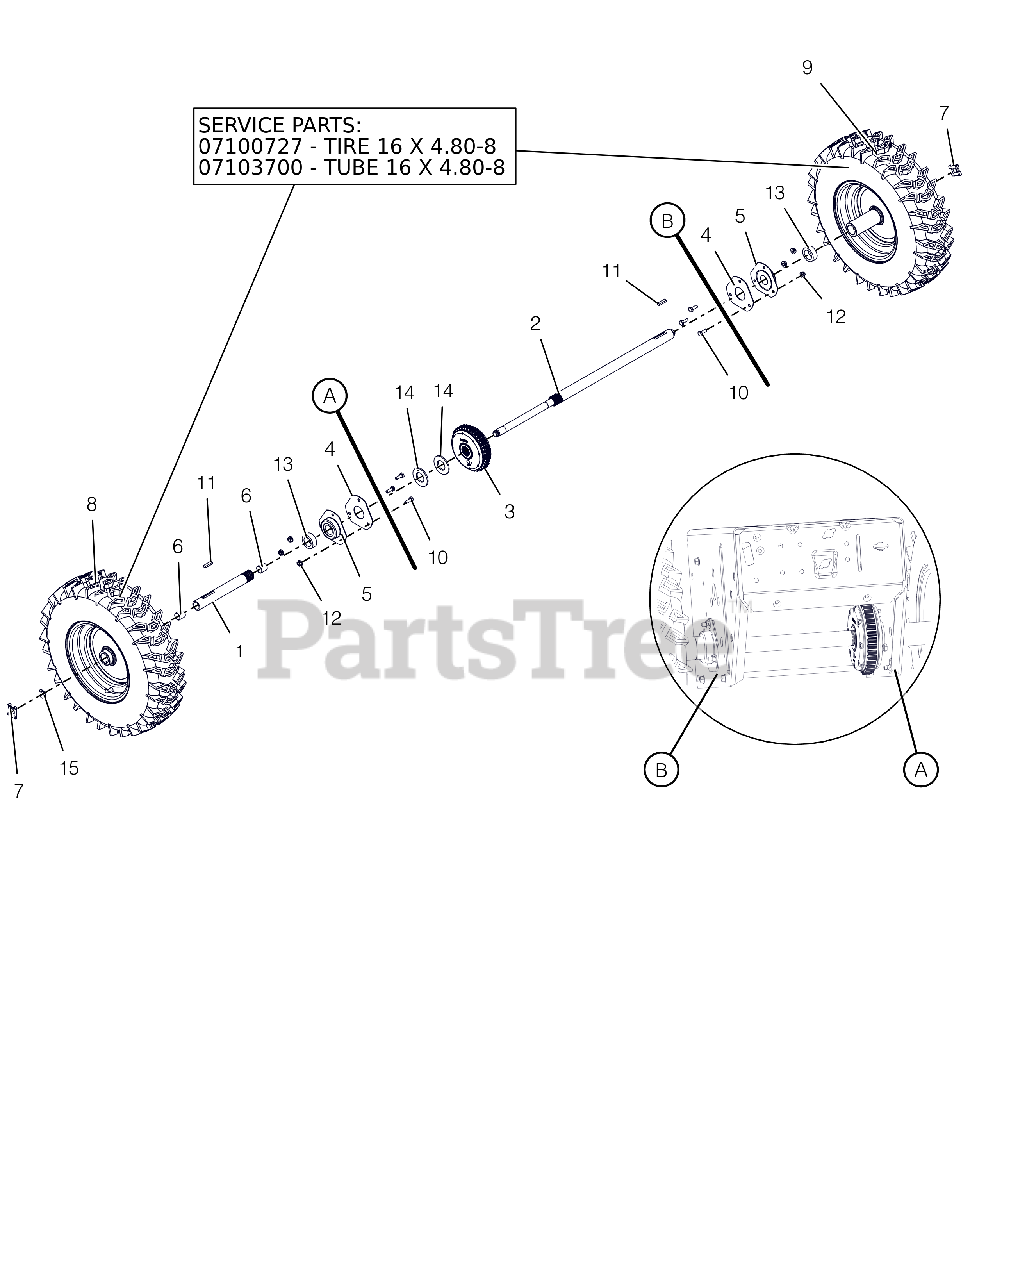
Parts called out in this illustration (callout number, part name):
1	AXLE, SHORT-AUTO W/BUSHINGS
2	AXLE, LONG-PRO AUTO DIFF
3	DIFFERENTIAL, AUTOMATIC
4	PLATE, BEARING SPACER
5	BRG-FLG 1.003/1.000 3 BOLT
6	BSHG-SLV .706X.764X.75 BRZ
7	CLIP, SNAP .625 DIA
8	TIRE/WHEEL,RH 16X4.8-8 DIFF T2
9	TIRE/WHEEL,LH 16X4.8-8 DIFF T2
10	@BLT-HEX .25-20X.75 GR5 YWZC
11	KEY-RECT .25X.188X1.00
12	@NUT-LK-CTR-FLG .25-20 YWZC
13	SPACER, PRO AXLE BEARING
14	WSHR-FL-STL- 1.062X2.0X.134 YZ
15	RG-RTNG-EXT .625X.042
16	TIRE, 4.80-8 K478
17	TUBE
